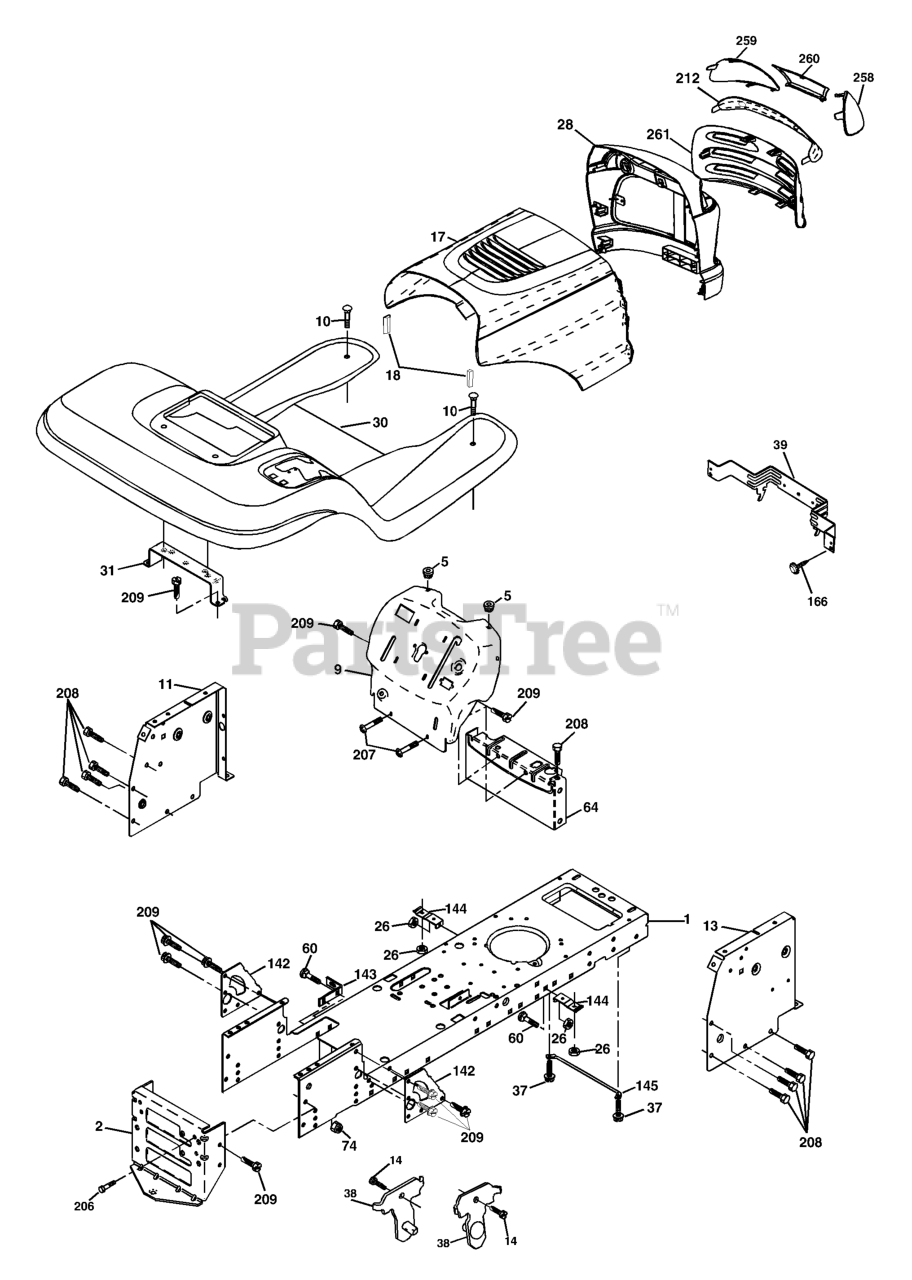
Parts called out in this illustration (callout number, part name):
1	CHASSIS STAMPING
2	DRAWBAR, 12GA
5	BUMPER.RUBBER.HOOD
9	DASH SILKSCR.
10	BOLT D
11	PANEL.DASH.LH.LTX
13	PANEL DASH RH
14	SCREW LT
17	HOOD
18	BUMPER.HOOD.LARGE.1.75"
26	NUT
28	GRILL/LEN.ASM.DL.HUSQ
30	FENDER FOOTREST
31	BRACKET.SUPPORT.FENDER
37	Screw Thdrol 5/16-18 x 1/2
38	BRACKET.ASM.PIVOT.MOWER.REAR
39	BRACKET PIVOT LASER
60	Bolt RDHD SQNK 3/8-16 x 3/4
64	DASH LOWER
142	PLATE REINFORCEMENT
143	BRACKET, SWAYBAR CHASSIS
144	BRKT, FOOT REST
145	ROD PIVOT CHASSIS/HOOD
166	SCREW
206	SHOULDER BOLT 5/16-18TT
207	SCREW, 5/16-18 X 1/2
208	SCREW 3/8-16X1/2
209	SCREW, 3/8-16X3/4
212	INSERT.LENS.REFLECTIVE
258	LENS LH
259	LENS LH
260	COVER.LENS.HUSQ.( HAVE GRAY)
261	INSERT GRILLE
